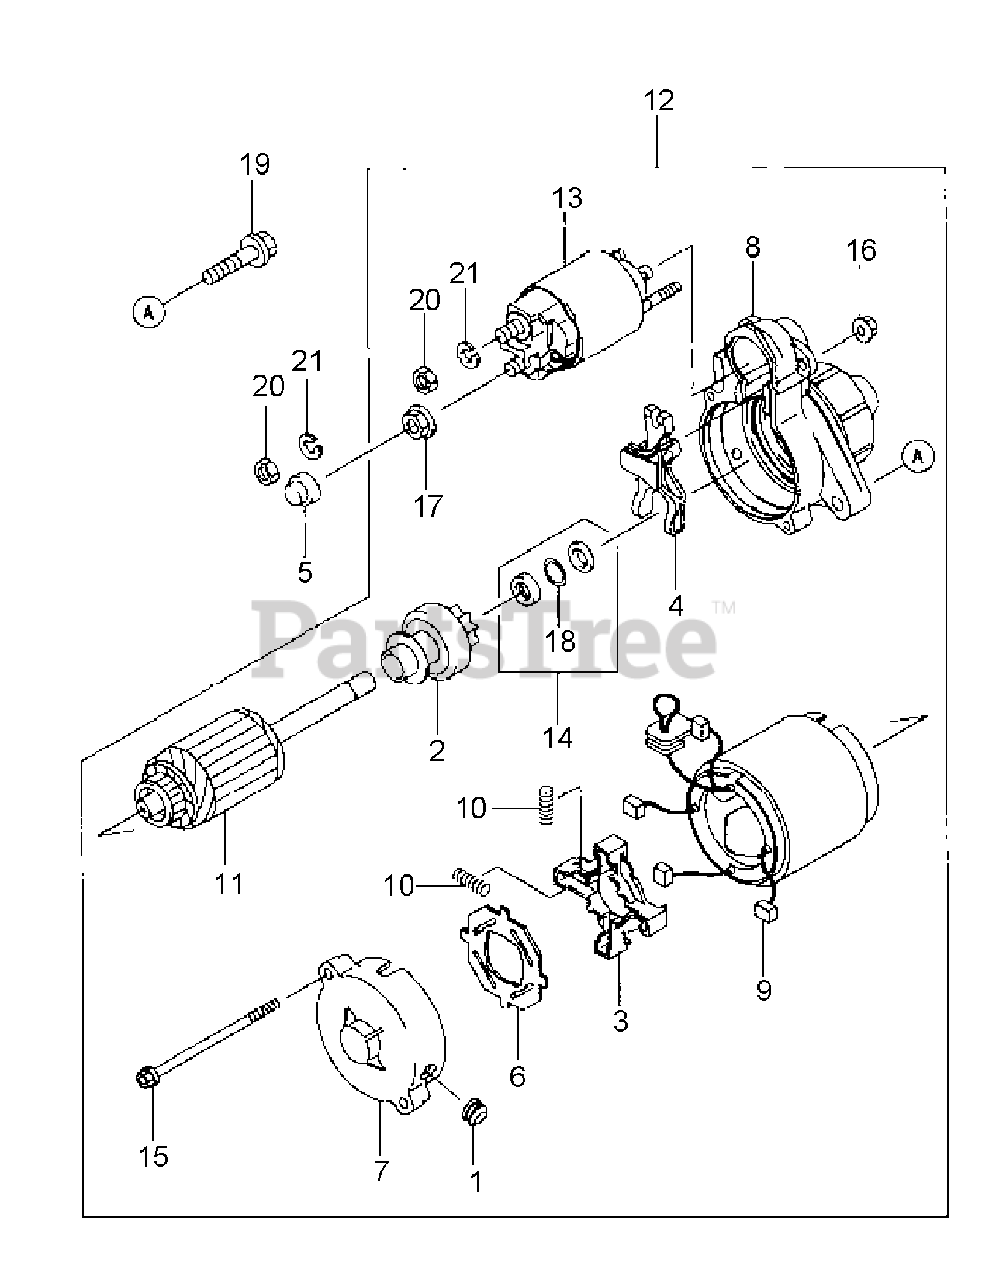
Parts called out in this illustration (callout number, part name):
12	ELECTRIC STARTER
19	FLANGED BOLT
20	HEX NUT SMALL
21	SPRING WASHER
